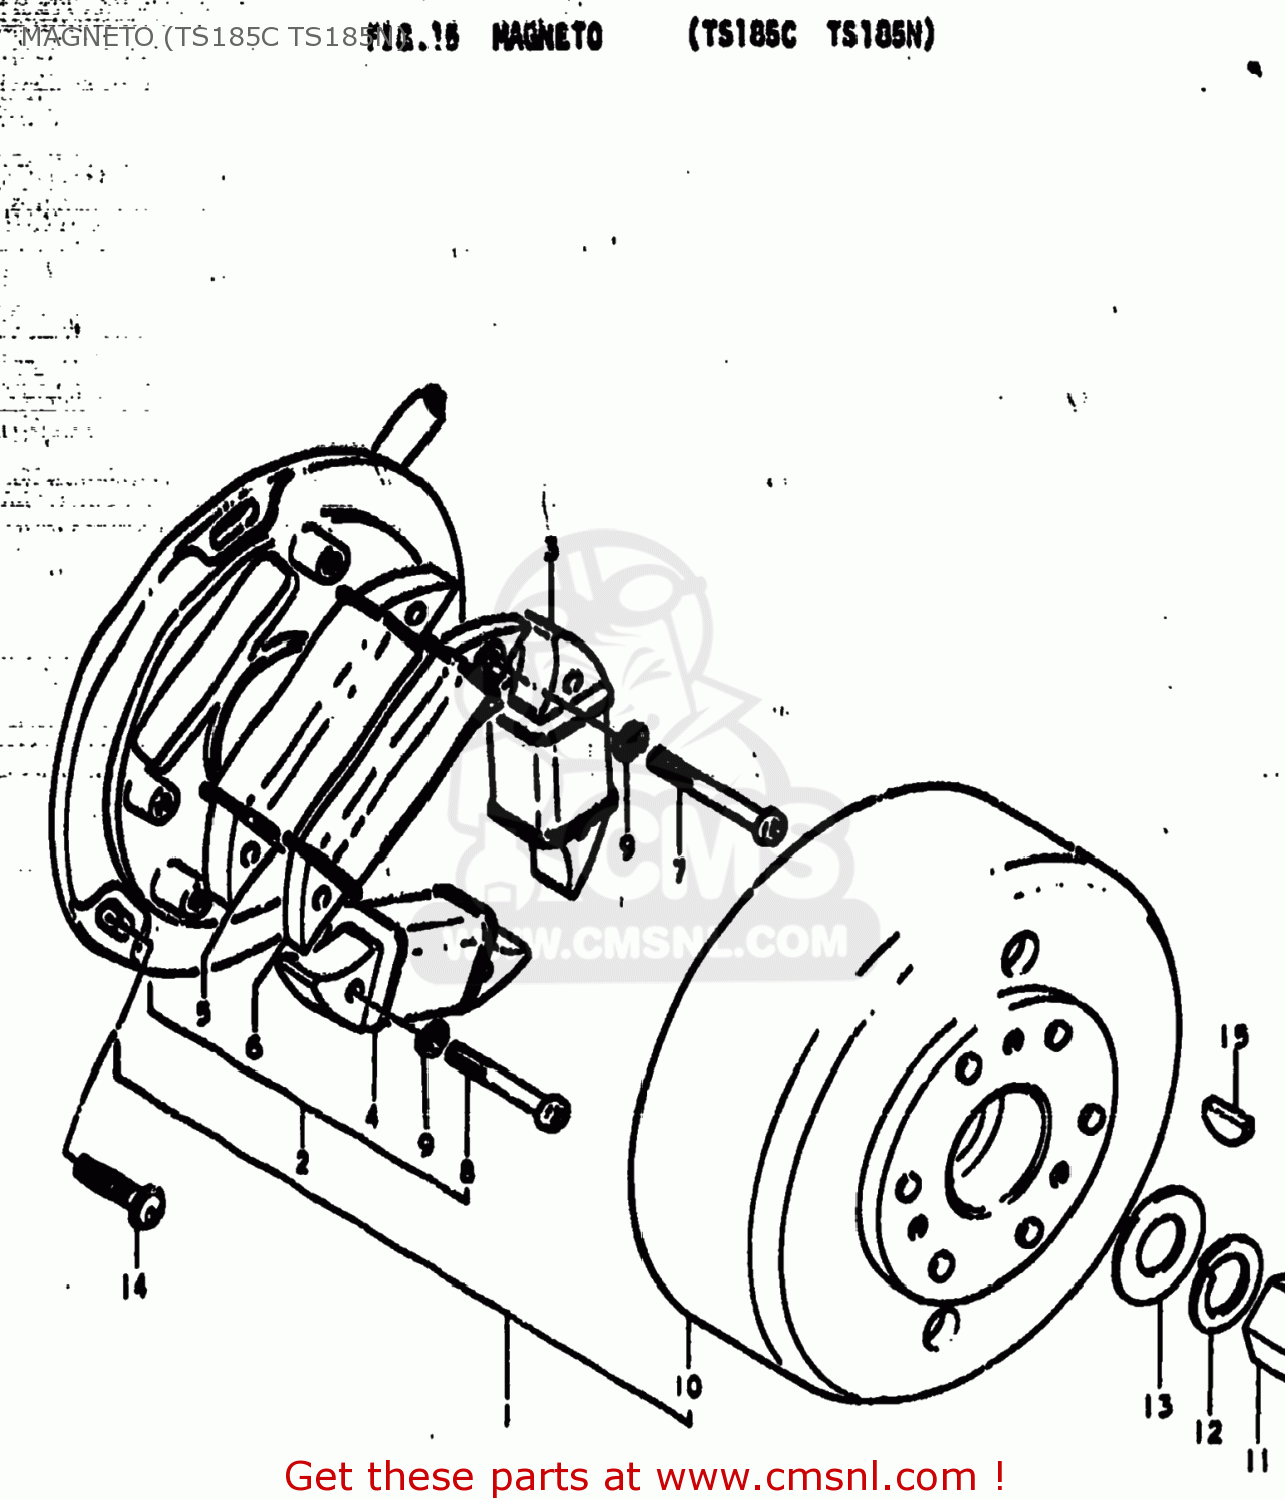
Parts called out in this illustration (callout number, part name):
1	MAGNETO ASSEMBLY
2	STATOR ASSEMBLY
3	COIL,CHARGE
4	COIL
5	COIL
6	COIL,PULSER
7	SCREW 5X35
8	SCREW 5X20
9	LOCK WASHER
10	ROTOR ASSEMBLY
11	NUT
12	LOCK WASHER
13	WASHER(14X27X3)
14	SCREW(5X14)
15	KEY 4MM
